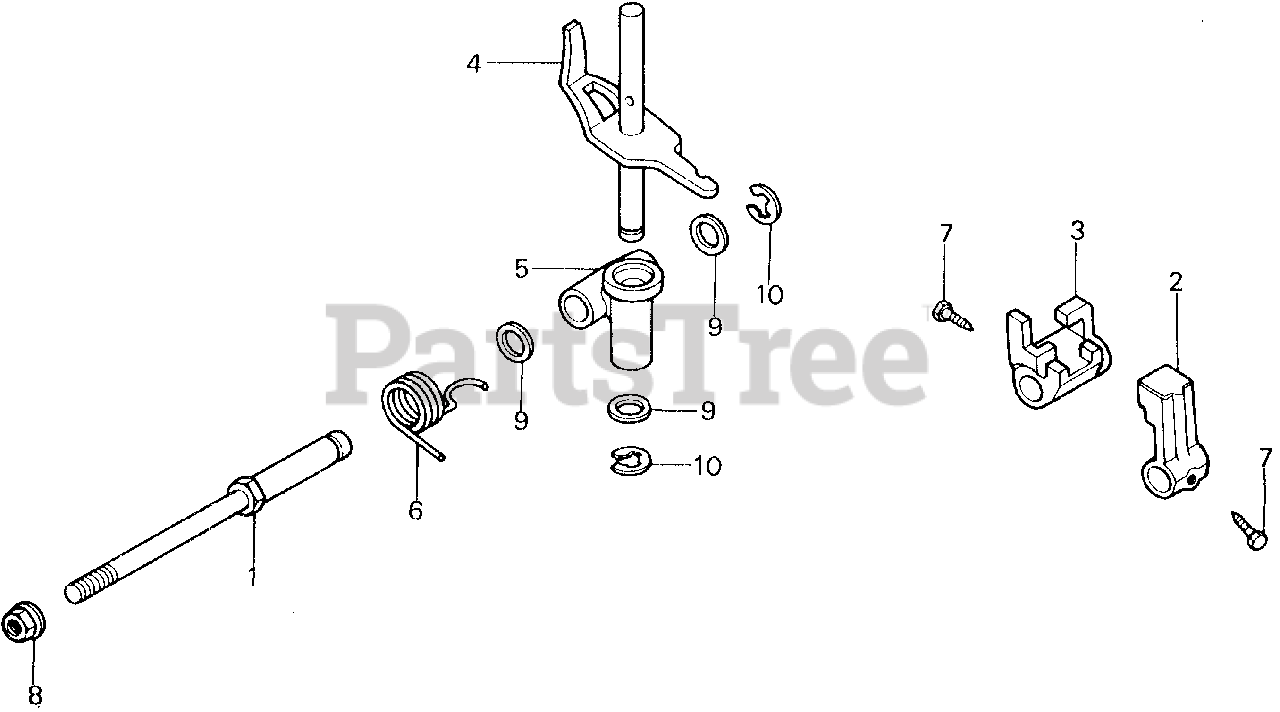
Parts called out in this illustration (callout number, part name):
1	BOLT, HOLDER
2	ARM A, CHANGE
3	ARM B, CHANGE
4	LEVER, SELECT
5	HOLDER, SELECT LEVER
6	SPRING, CHANGE LEVER RETURN
7	SCREW, FORK SETTING
8	NUT, FLANGE (10MM)
9	WASHER, PLAIN (12MM)
10	E-RING (10MM)
